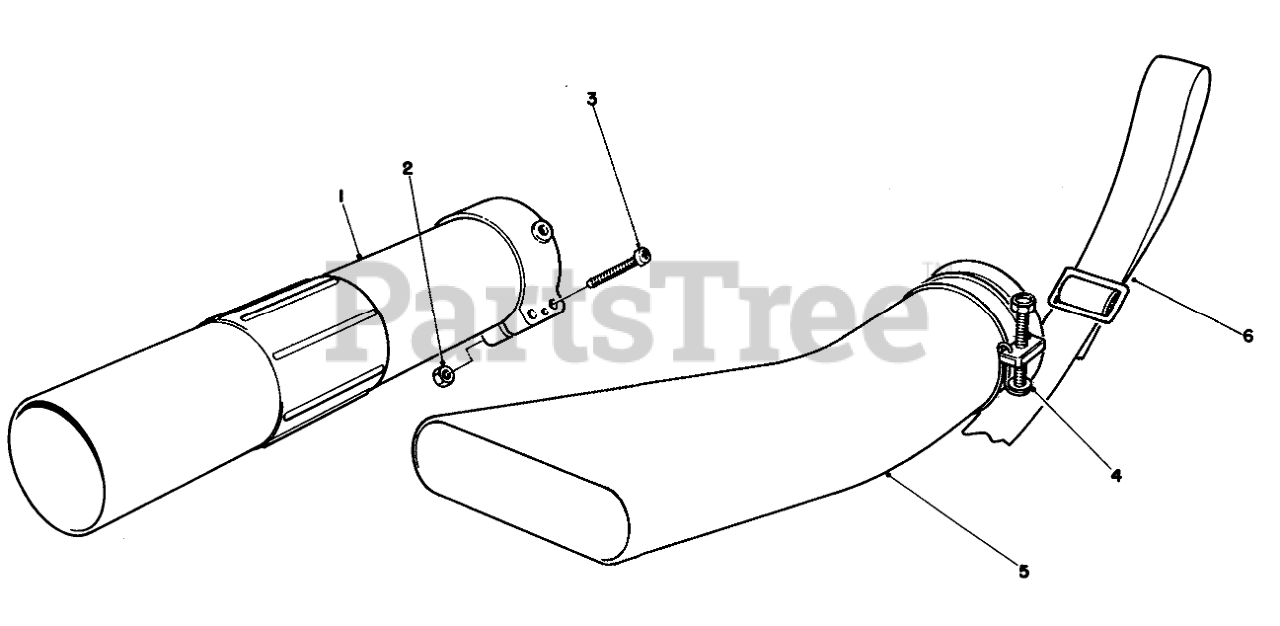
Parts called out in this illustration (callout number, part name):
1	STRAIGHT PIPE
2	INSULATOR NUT
3	SCREW
4	HOSE CLAMP
5	END PIPE
6	STRAP
